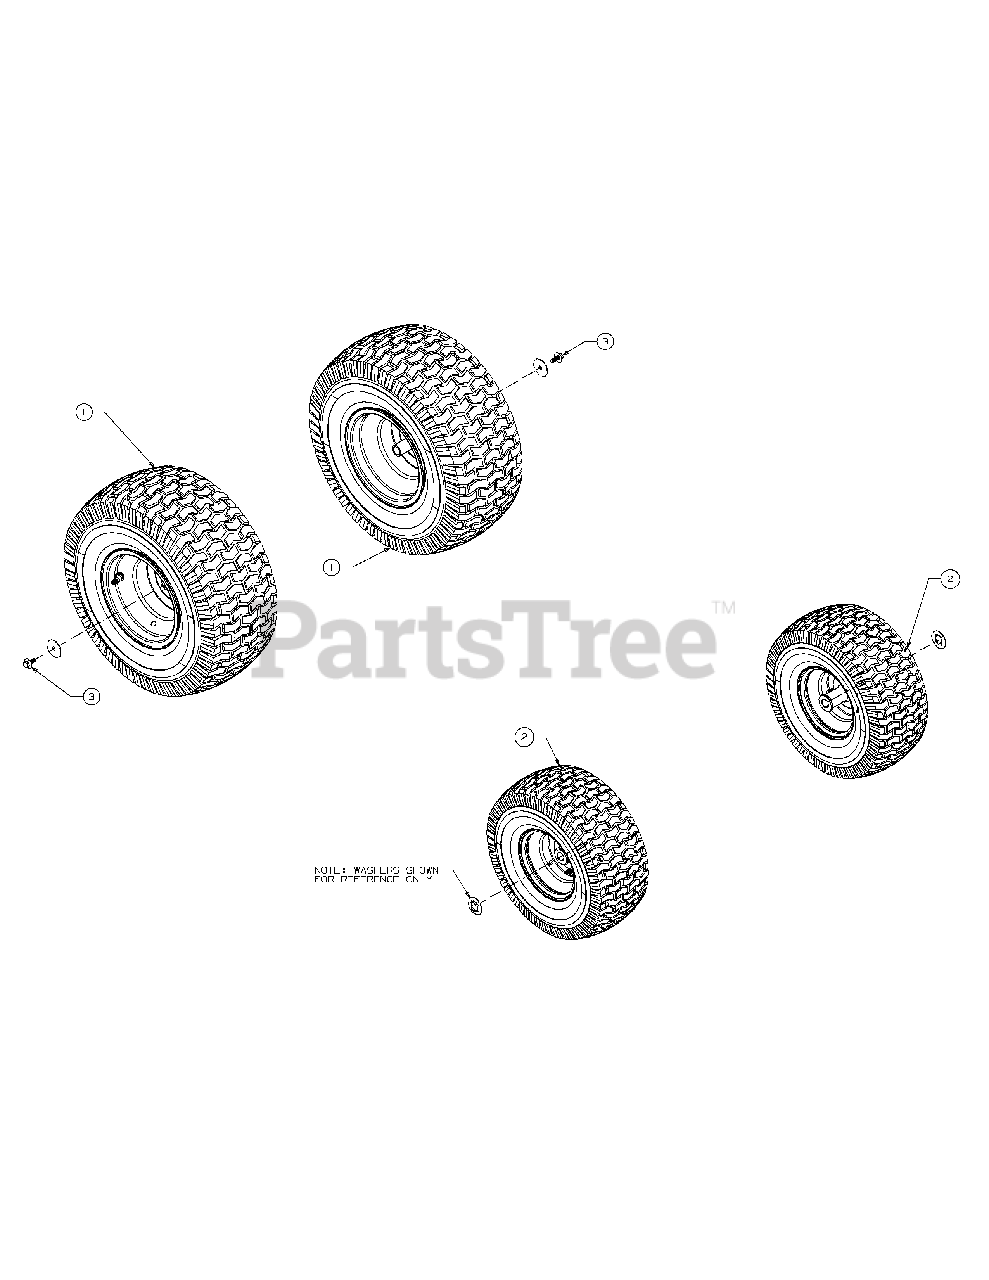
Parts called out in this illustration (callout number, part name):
1	Wheel Assy Comp
1	Rim Asm-8.0 X 7.0
1	Valve:Tire:Tubeless
1	Tire-20X8 Multi
2	Wheel-Comp 15X6X6
2	Rim Asm-6.0 X 4.5
2	Valve:Tire:Tubeless
2	Bearing-Flange, Front Wheel
2	Fitting-Grease
3	Hhcs 5/16-24 X .85 Sems Gr5 Patch
